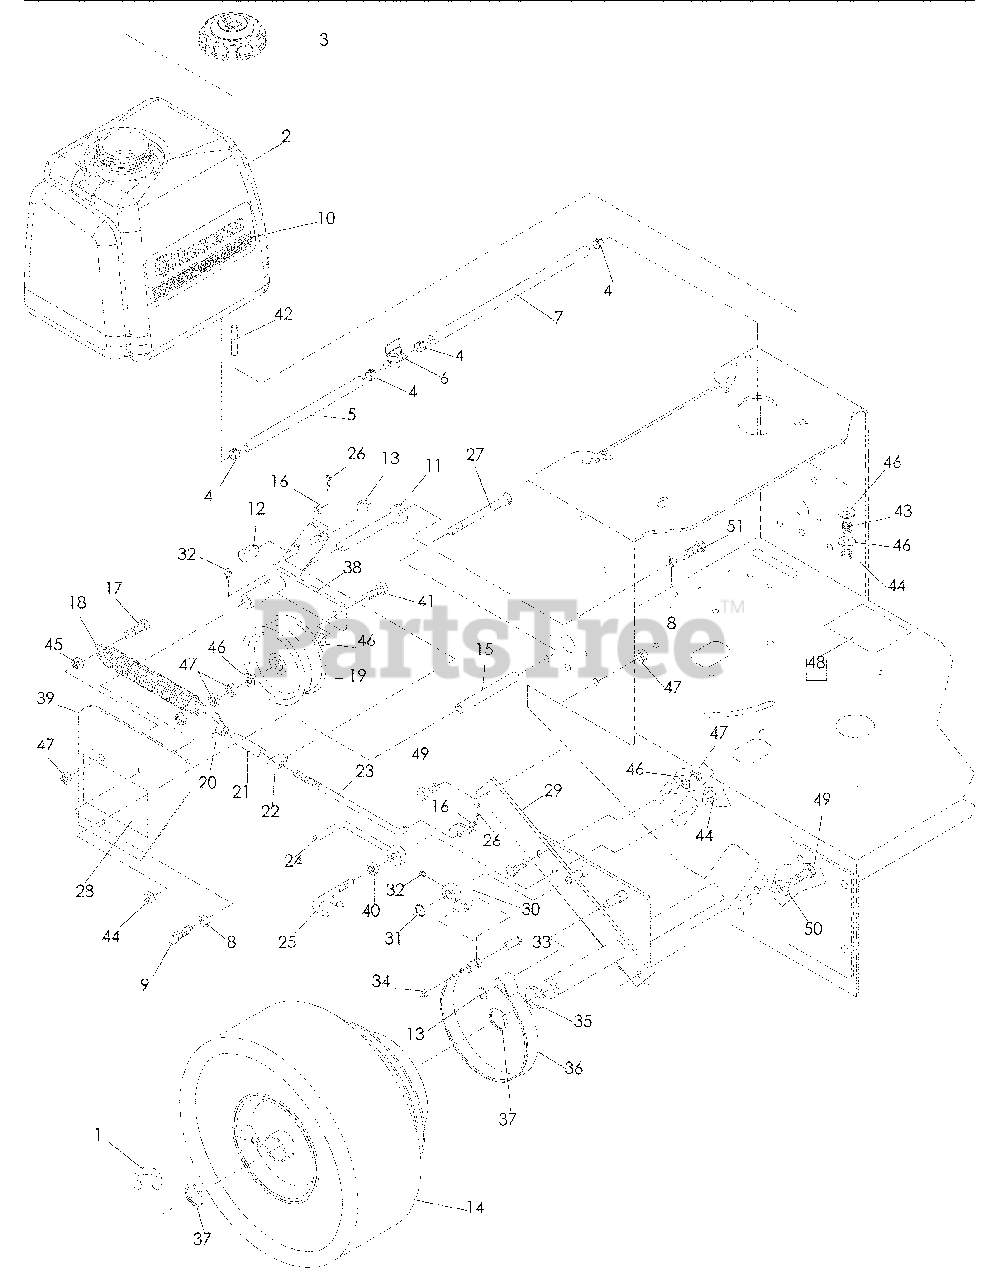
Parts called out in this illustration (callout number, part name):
1	E-RING, 1"
3	GAS CAP
4	HOSE CLAMP
5	GAS LINE, 10"
6	FUEL VALVE
7	GAS LINE, 14"
8	LOCKWASHER 5/16
9	HCS 5/16-18 x 1
10	DECAL, W3213
11	PIVOT TUBE
12	SWIVEL(SHORT)
13	E-RING, 3/8"
14	WHEEL ASSM (32) (WITH BRAKE DRUM & PULLEY)
15	LONG SPACER
16	WASHER 5/16
17	HCS 3/8-16 x 1¼
19	IDLER PULLEY
20	WINGNUT 5/16
24	BELT GUIDE
25	SCRAPER (36 & 48)
26	COTTER HAIRPIN, #2
27	HCS 5/16-18 x 5
28	DECAL, CROWN
29	AXLE WLDMT(36 & 48)
30	BRAKE ARM, RT
32	ZERK, ¼-28 STRAIGHT
33	CLEVIS PIN
34	BOLT RETAINER, 3/8
36	BRAKE BAND
38	IDLER PLATE, RT
40	NUT 5/16-18 WHIZLK
41	TAPBOLT 3/8-16 x 3
44	NUT 5/16-18
45	NUT 3/8 -16 WHIZLK
46	WASHER 3/8
47	NUT 3/8-16 CENTERLOCK
48	DECAL, PROP 65
49	HCS 3/8-16 x 1
50	LOCKWASHER 3/8
